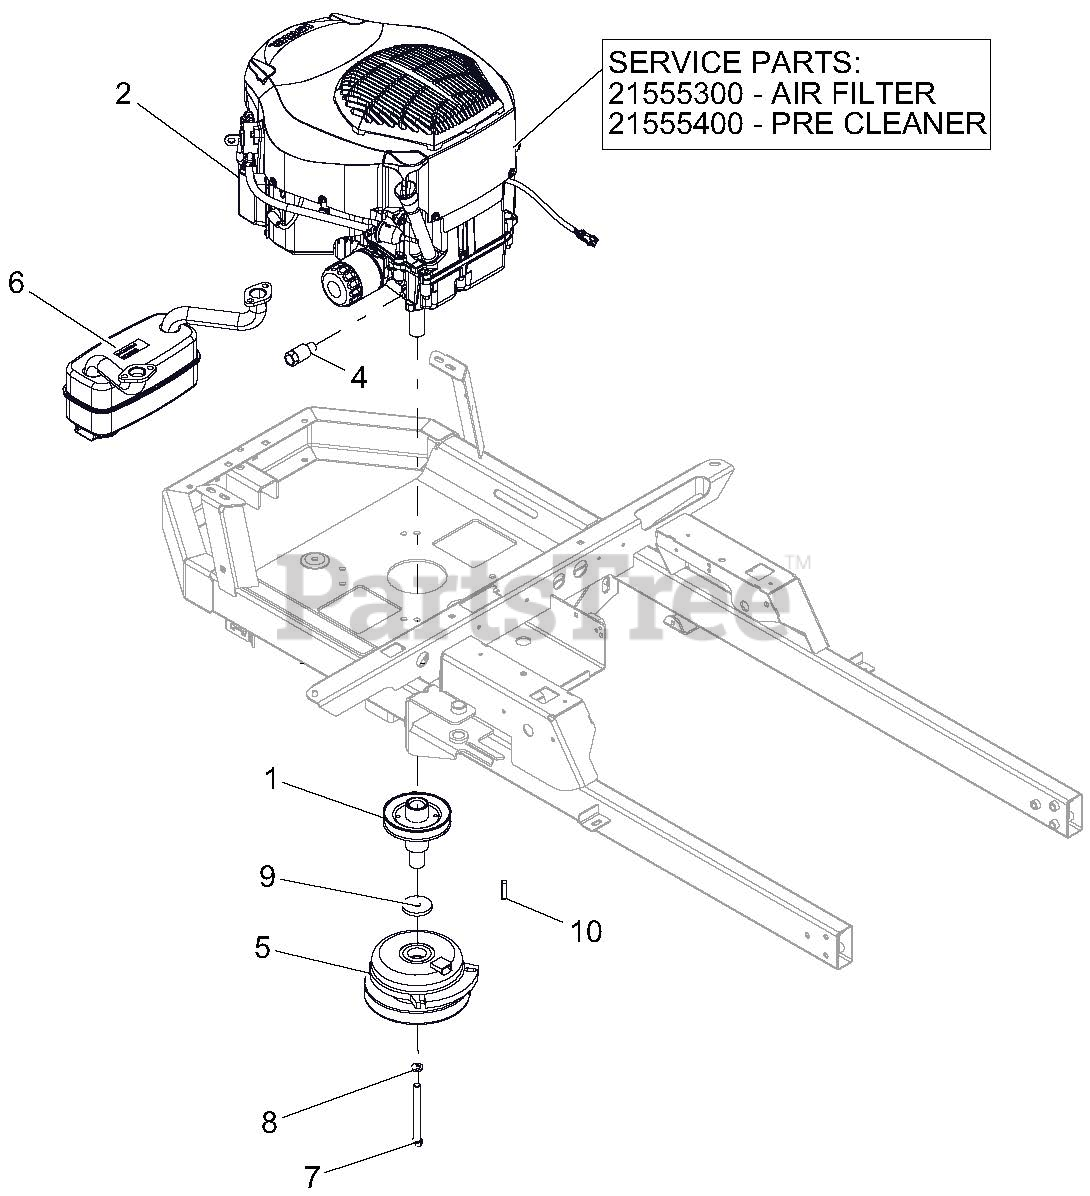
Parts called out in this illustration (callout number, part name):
1	WLDMT, DRIVE SHEAVE
2	ENGINE, KOHLER PRO24 W/SC
2	AIR FILTER
2	PRE CLEANER
4	DRAIN, OIL
5	CLUTCH, ELEC 105 FT LB MONOPOLE 6.83"
6	MUFFLER, KOHLER
7	BLT-HEX .44-20X4.50 GR8 YWZC
8	WSHR-LK .44X.109 REG YWZC
9	WSHR-FL-STL .469X2.00X.25 YWZC
10	KEY-SQ .250X.250X1.250
